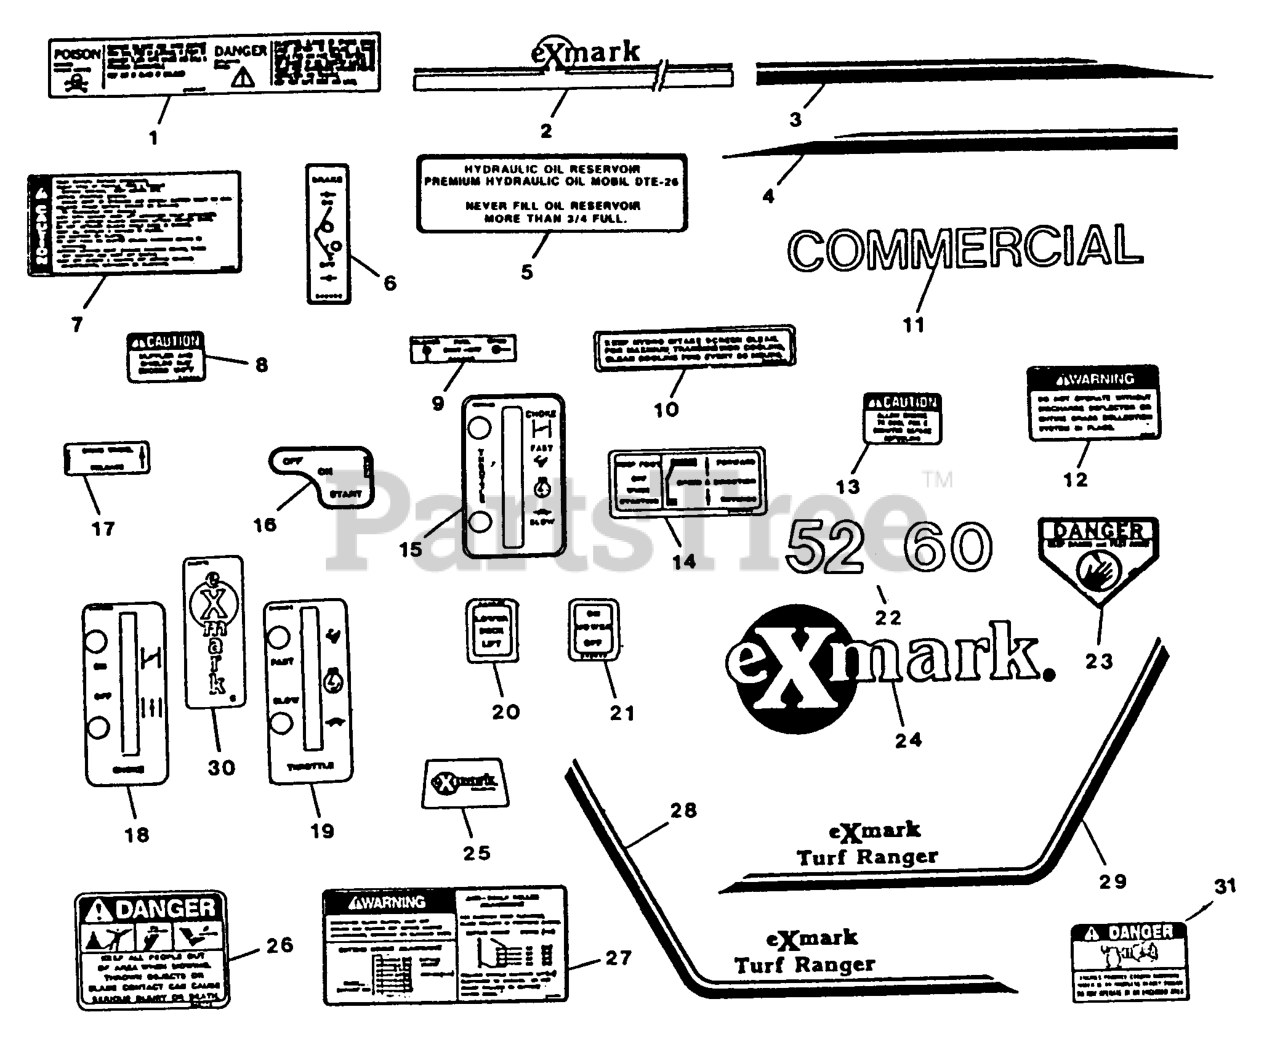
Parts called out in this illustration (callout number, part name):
1	DECAL-BATTERY
10	DECAL,INTAKE
14	DECAL,FOOT PEDAL
20	DECAL-DECK LIFT
21	DECAL-MOWER SWITCH
23	DECAL-DANGER
26	DECAL-DANGER
